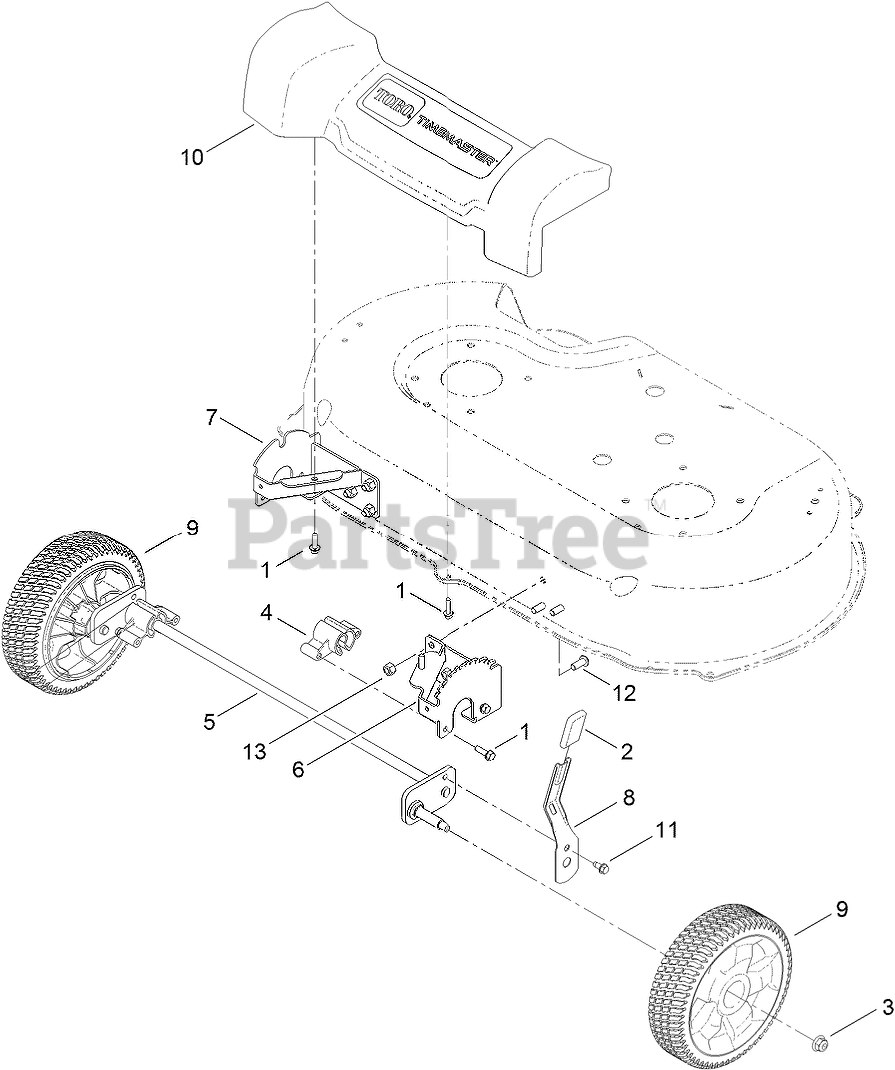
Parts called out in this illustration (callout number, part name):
1	SCREW-HWH
2	GRIP-LEVER
3	NUT-HF, NI
4	BUSHING-PIVOT, FRONT
5	AXLE-FRONT
6	PLATE-HOC, LH
7	PLATE-HOC, RH
8	ARM-SPRING
9	8 INCH WHEEL ASM
10	FRONT COVER ASM
11	SCREW-HWH
12	SCREW-HSBH
13	NUT-LOCK, NI
